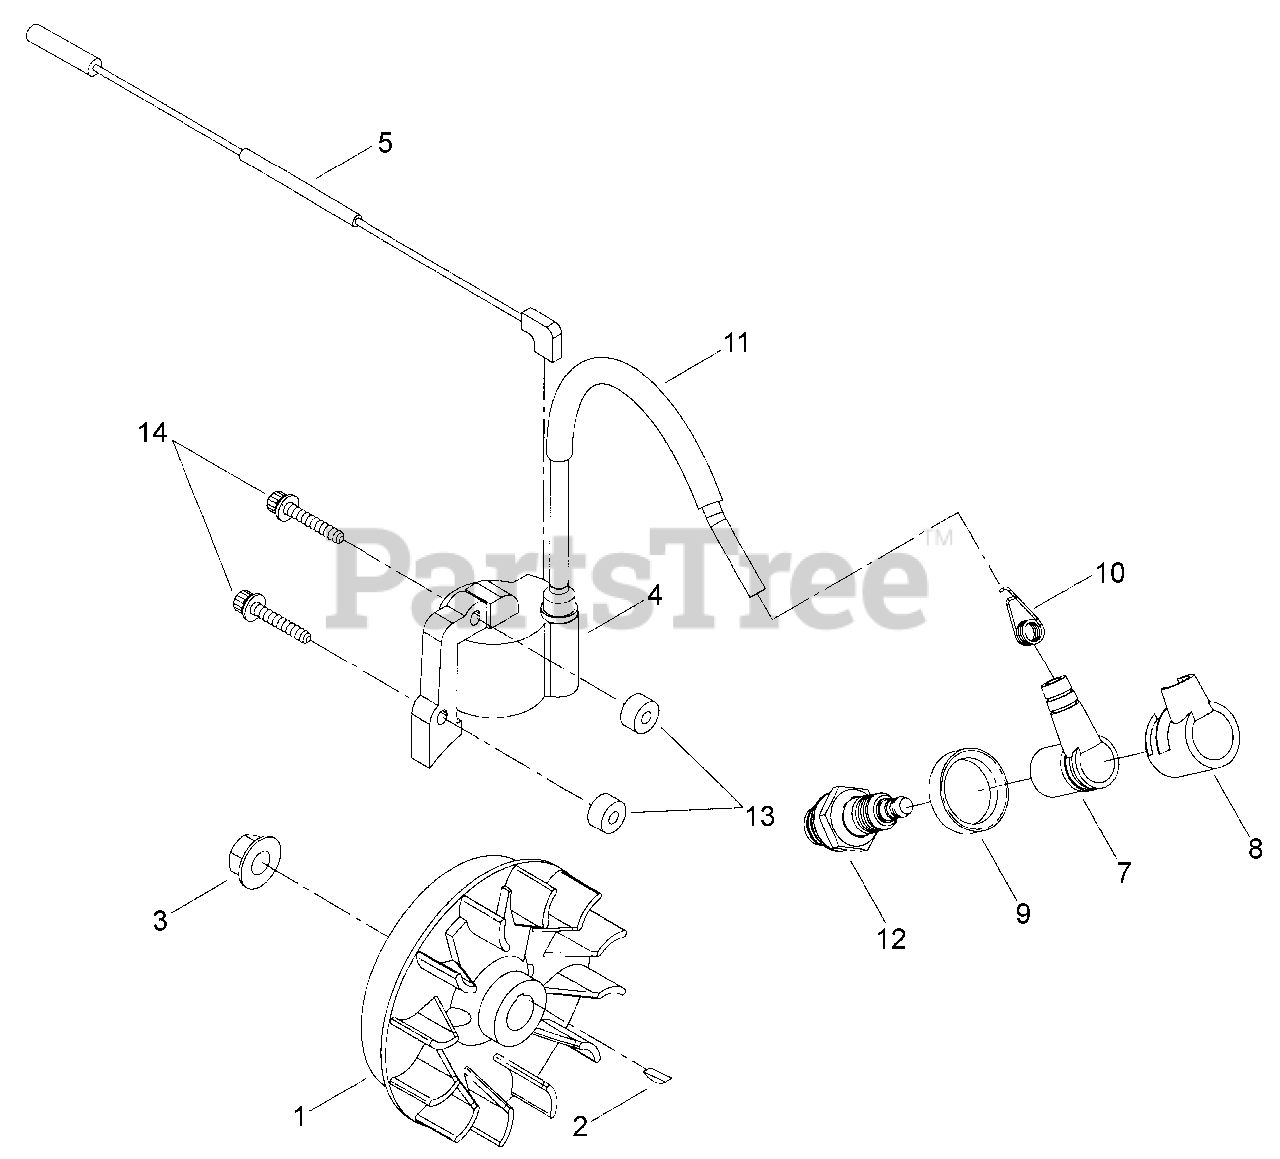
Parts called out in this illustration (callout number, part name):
1	FLYWHEEL
2	KEY - 3X10
3	NUT - 8
4	COIL, IGNITION
5	LEAD - IGNITION
7	CAP, SPARK PLUG
8	CAP, SPARK PLUG
9	SEAL, DUST
10	TERMINAL, SPARK PLUG CAP
11	TUBE
12	SPARK PLUG -- CJ-8Y
13	INSULATOR
14	SCREW - 4X26
